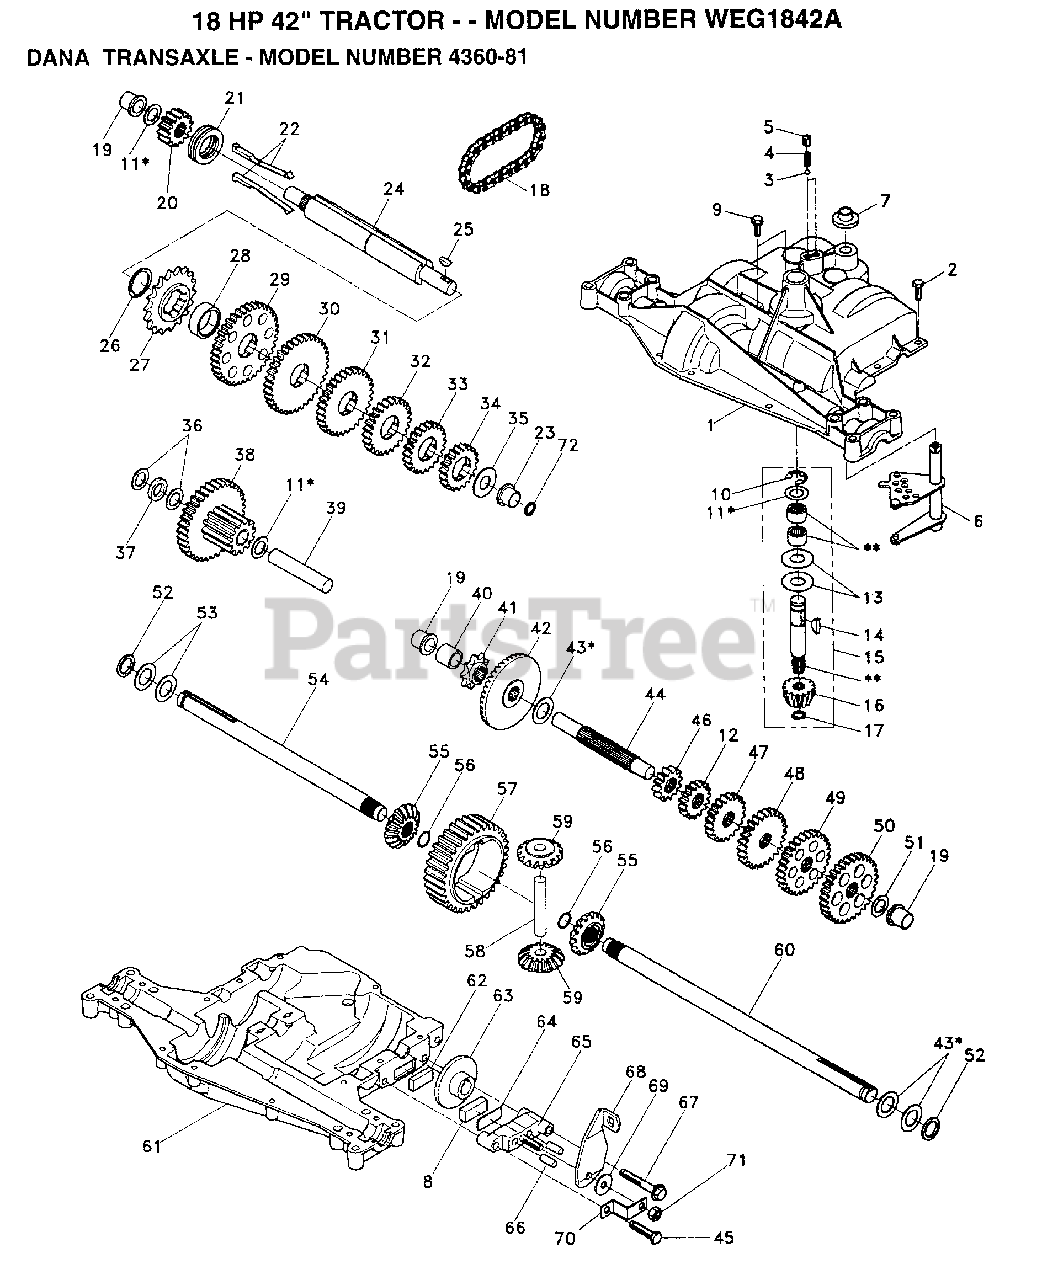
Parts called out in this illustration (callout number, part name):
1	HOUSING UPPER TRN
4	"SPRING, DETENT LT"
5	"SCREW, SET LT"
6	SHIFTER.ASM.KIT.
7	SHIFTER BOOT
8	PUCK T
9	SCREW TAP W/SEAL
11	ASM KIT SHIM 4689
12	GEAR SPUR 15 TTH
13	WASHER T
14	KEY WOODRUFF-DANA
17	"RING,RETAINING LT"
18	"CHAIN,24 PTCH LT"
19	"CHAIN,24 PTCH LT"
20	GEAR SPUR 14 TTH
21	COLLAR CLUTCH
22	KIT.ASM.CLUTCH KY
24	SHAFT INTERM DANA
25	WOODRUFF KEY
26	"RING,RETAINING LT"
27	SPROCKET 18T T
28	SPACER YT
29	GEAR SPUR 37 TTH
30	GEAR SPUR 35 TTH
32	GEAR 25T LT
33	GEAR SPUR 22 TT
34	SPUR GEAR 19T
35	"WASHER, PLAIN LT"
36	WASHER 025
37	SPACER
38	ASSM GEAR COMB
39	SHAFT IDLER
40	SPACER T
41	SPROCKET 9T LT
43	ASM KIT SHIM
44	SHAFT T
45	"SCREW, TAPPING LT"
46	GEAR SPUR 12 TTH
48	"GEAR, SPUR 25T LT"
49	GEAR 28T T
50	"GEAR, SPUR 31T LT"
51	WASHER 060
52	NEOPRENE WASHER
53	WASHER 031
55	GEAR LT
56	"RING,RETAINING LT"
58	SHAFT T
59	"GEAR,MITER 15T YT"
61	HOUSING LOWER TNS
62	PUCK T
63	BRAKE DISC. T
64	SPACER LT
66	PIN T
69	WASHER LT
71	NUT.LOCK.5/16-24
72	SEAL OIL DANA5416
